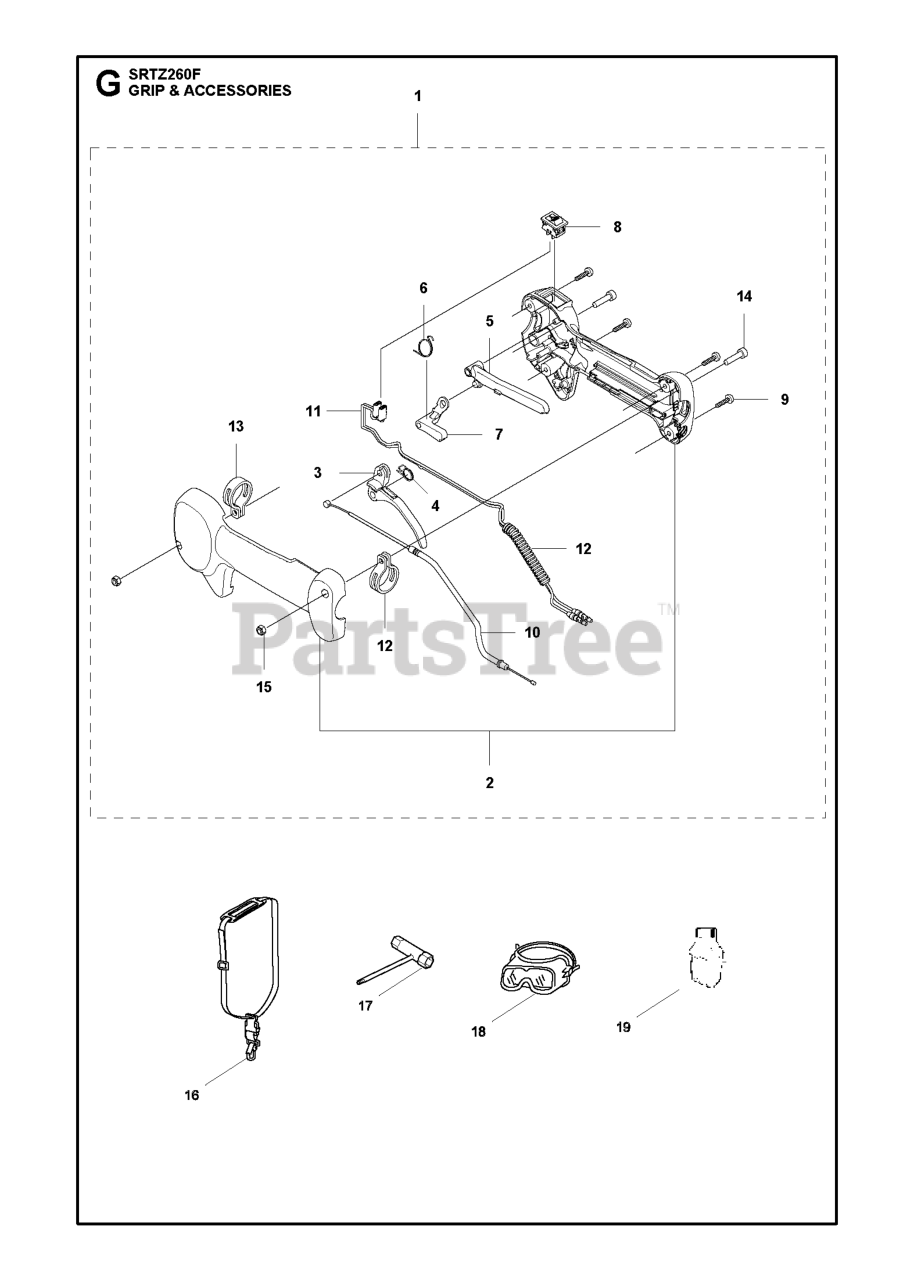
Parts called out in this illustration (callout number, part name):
1	ASSY THROTTLE
2	GRIP HALF SET
3	LEVER, THROTTLE
4	SPRING, THROTTLE
5	LEVER, SAFETY
7	LEVER JOINT
8	STOP SWITCH NM_09091801
11	CORD - C
15	NUT
16	STRAP ASSY
17	COMBINATION WRENCH TORX
18	GOGGLExxx (RPLS
19	OIL 2 CYCLE ENGINE OIL 2.
